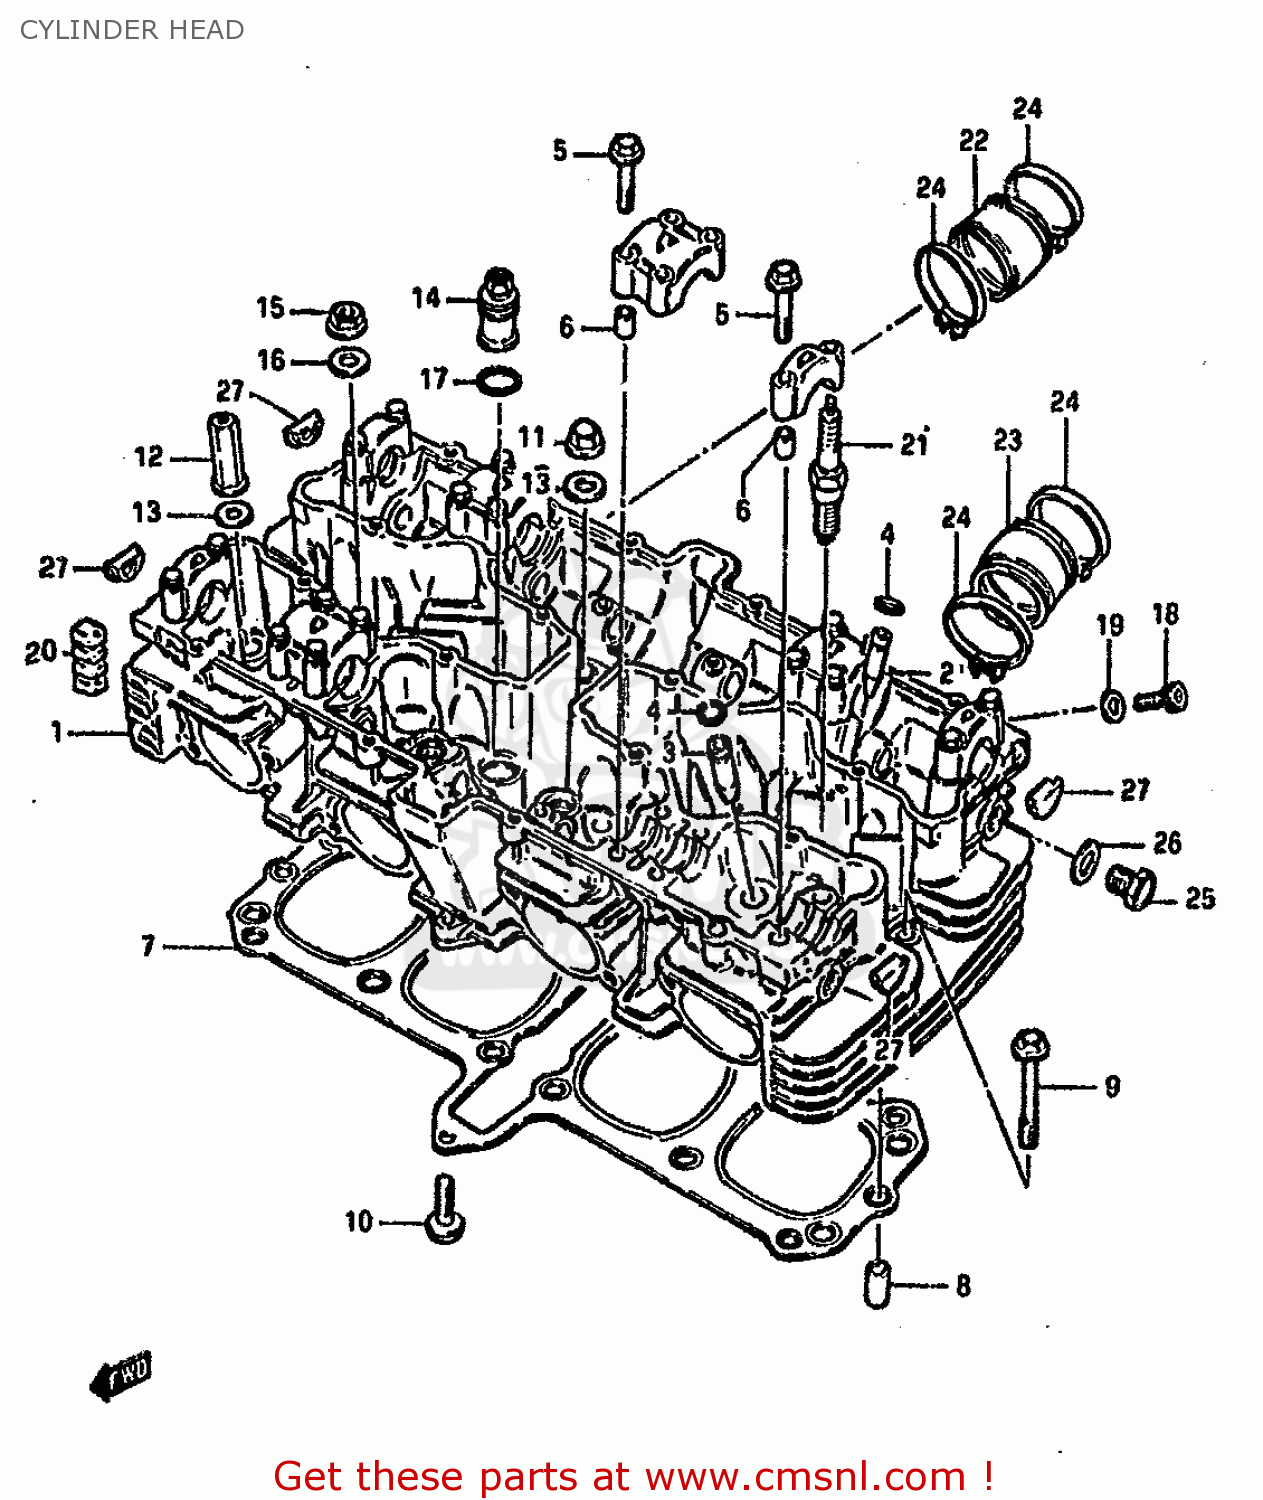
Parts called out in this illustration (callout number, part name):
1	HEAD SET,CYLINDER
2	GUIDE,INTAKE VALVE
3	GUIDE,INTAKE VALVE
4	RING,SNAP
5	BOLT(6X39)
6	PIN(6.2X8X11)
7	GASKET,CYLINDER HEAD (NAS)
8	PIN
9	BOLT
10	BOLT
11	NUT
12	NUT
13	GASKET(10.5X22X2) (NAS)
14	NUT,CYLINDER HEAD SEAL
15	NUT
16	WASHER(10.5X22X2.3)
17	O RING(D:2.4,ID:16.8)
18	BOLT
19	GASKET(5.3X9.3X1.2) (NAS)
20	PAD,CYLINDER
21	SPARK PLUG D8EA
22	PIPE,INTAKE,R
23	PIPE,INTAKE
24	CLAMP
25	PLUG (14X12)
26	GASKET(14X19.2X2) (NAS)
27	PLUG
